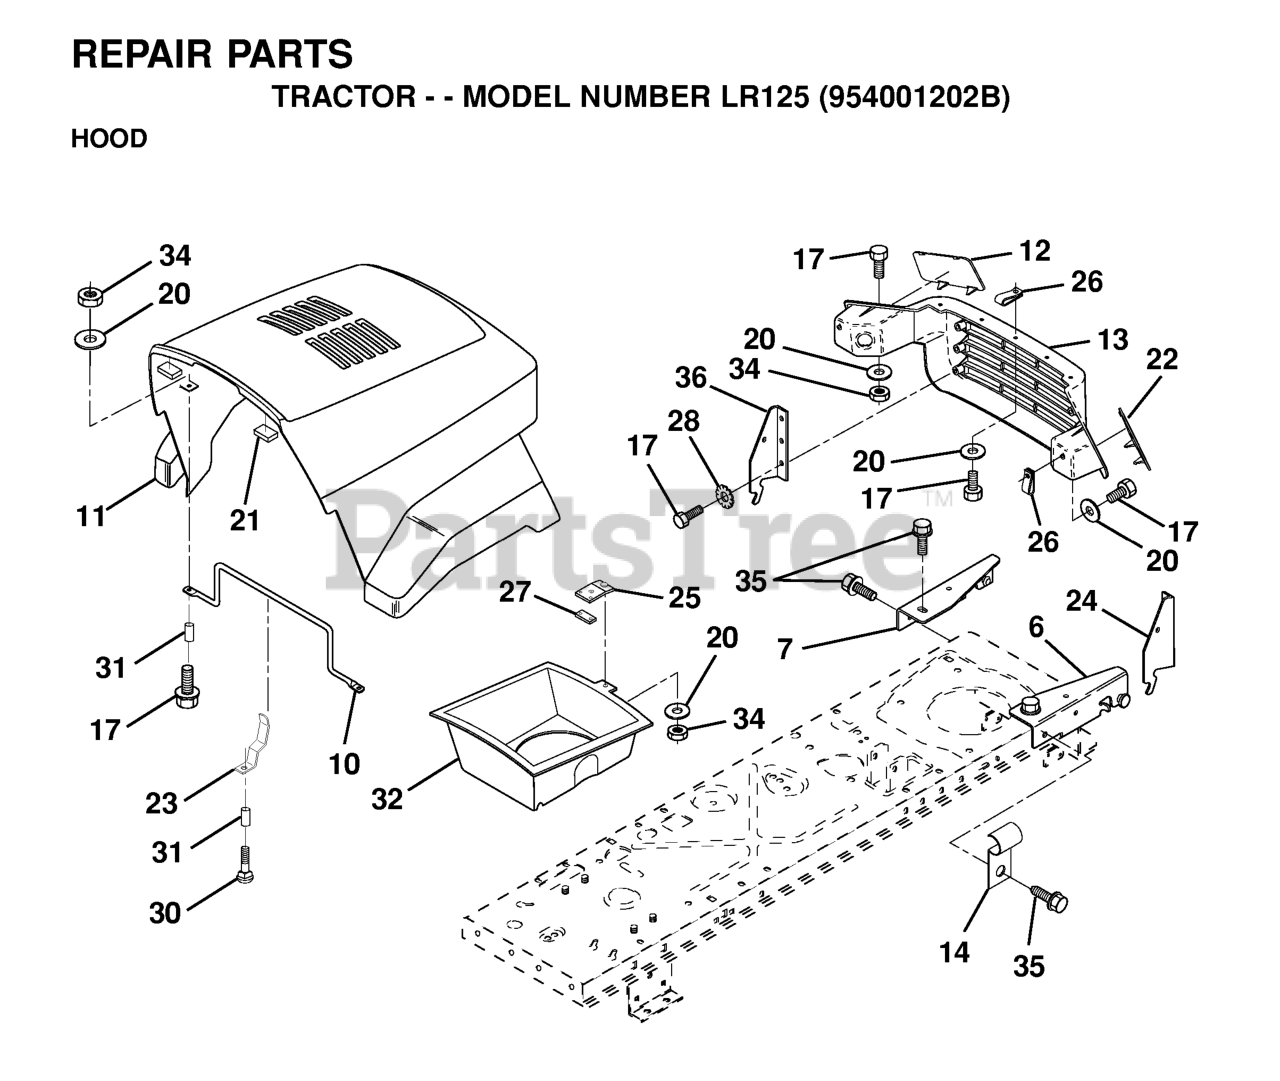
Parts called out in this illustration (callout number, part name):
3	BRACKET HOOD
6	BRACKET ASSY HOOD
7	BRACKET ASSY
10	BRACE HOOD
12	LENS.LR.LH.HUSQV.
13	GRILL
14	CLIP T
17	BOLT
20	WASHER
21	BUMPER HOOD T
23	HOOD LATCH
24	BRACKET PIVOT
26	CLIP TINNERMAN
28	Washer, Lock, External Tooth 1/4
30	Bolt Rdhd. Sht. Nk 1/4-20 x 1-3/8
33	Bolt Hex Fin 1/4-20 Unc x 1-1/2
34	NUT.CROWNLOCK.1/4
35	SCREW.THDROL.5/16-18X3/4.TTY
